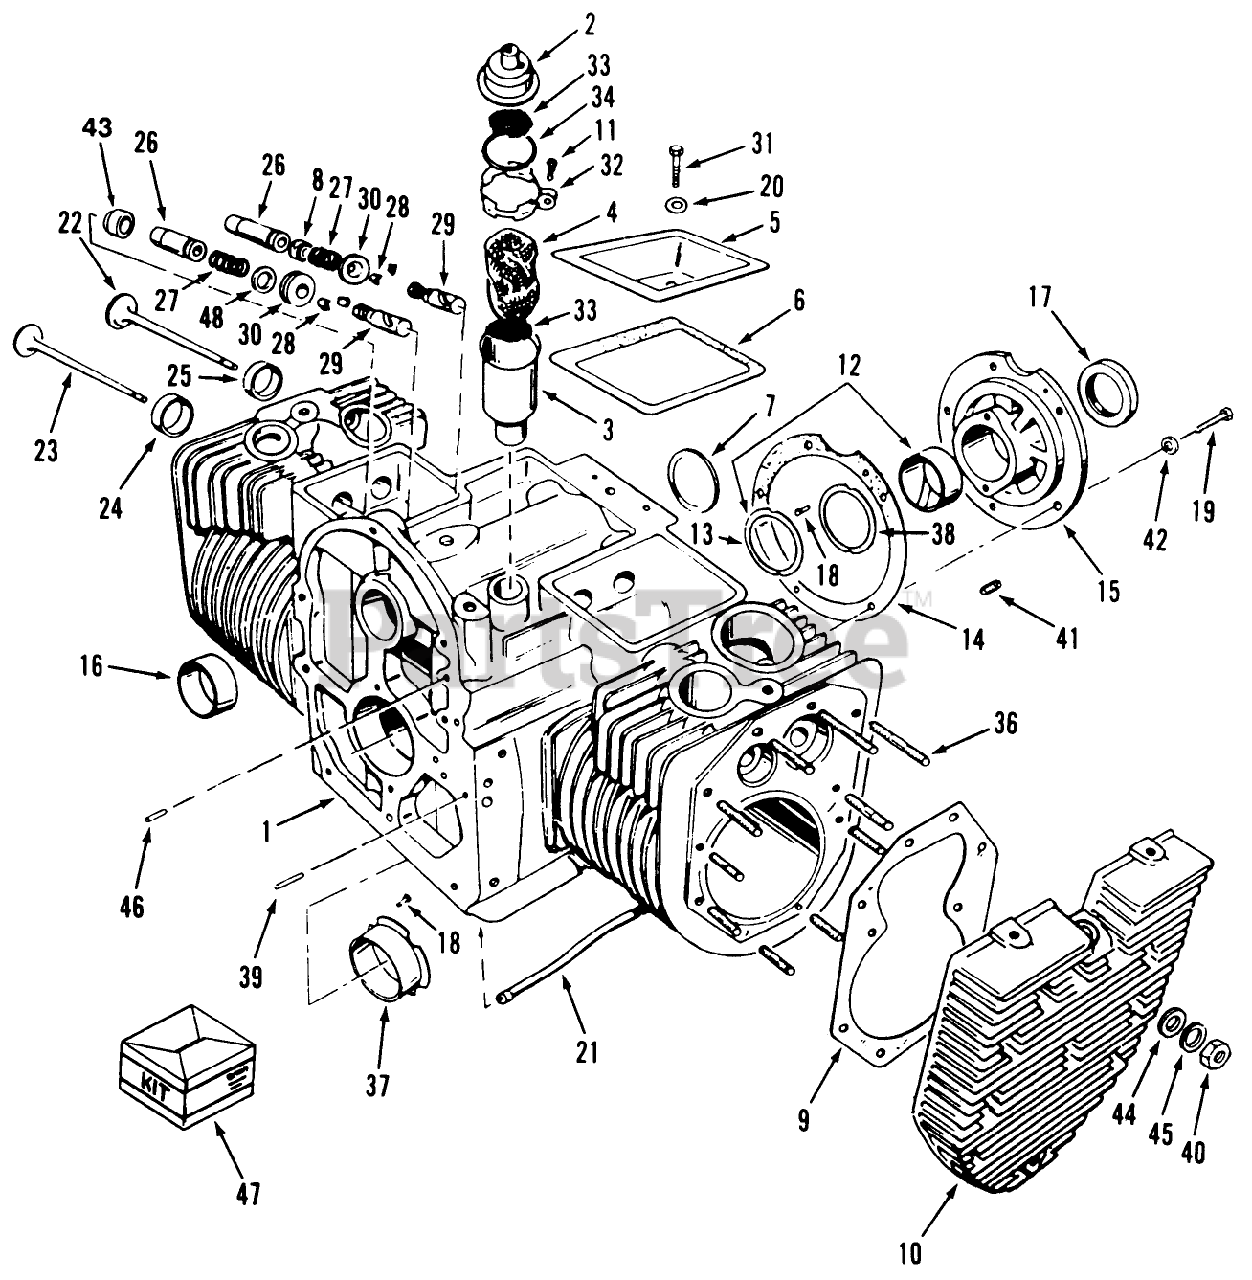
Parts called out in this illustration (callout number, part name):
1	Short Block 24HP (Incl. Ref. #3, 7, 13-16, 18, 21, 24-26, 30, 36, 38 & 39)
2	BREATHER-CAP AND VALVE
3	TUBE-BREATHER
4	FILTER
5	COVER-VALVE COMPARTMENT
6	GASKET-VALVE COVER
7	Plug
8	SUPPORT-AIR CLEANER
9	GASKET-CYLINDER HEAD
10	HEAD-CYLINDER
11	SCREW-TAPPING, ROUND HEAD
12	BEARING KIT (STANDARD SLEEVE)
13	Thrust Washer
14	GASKET
15	Plate-Bearing
16	SLEEVE-BEARING
17	Oil Seal
18	PIN-DRIVE
19	HEX HD CAPSCREW
20	Washer
21	TUBE-OIL, CRANKCASE
22	Intake Valve
23	Exhaust Valve
24	INSERT
25	Insert-Intake Seat STD
26	GUIDE-VALVE, EXHAUST
27	Spring-Valve
28	LOCK-VALVE SPRING
29	TAPPET
30	ROTOCAP
31	SCREW - CAP HEX HEAD
32	Clamp
33	SCREEN-BREATHER TUBE
34	SEAL - O-RING
36	Mtg. Stud-Cylinder Hd (Install 4 Bottom Holes LH, RH Hd)
37	KIT-BEARING, SLEEVE
38	Shim 0.005"
39	Pin
40	NUT-HEX
41	Screw
42	Washer
43	Cap-Exhaust Valve
44	Washer
45	WASHER-LOCK, COMPRESS
46	Plug
47	KIT-GASKET CARB REM
48	WASHER
